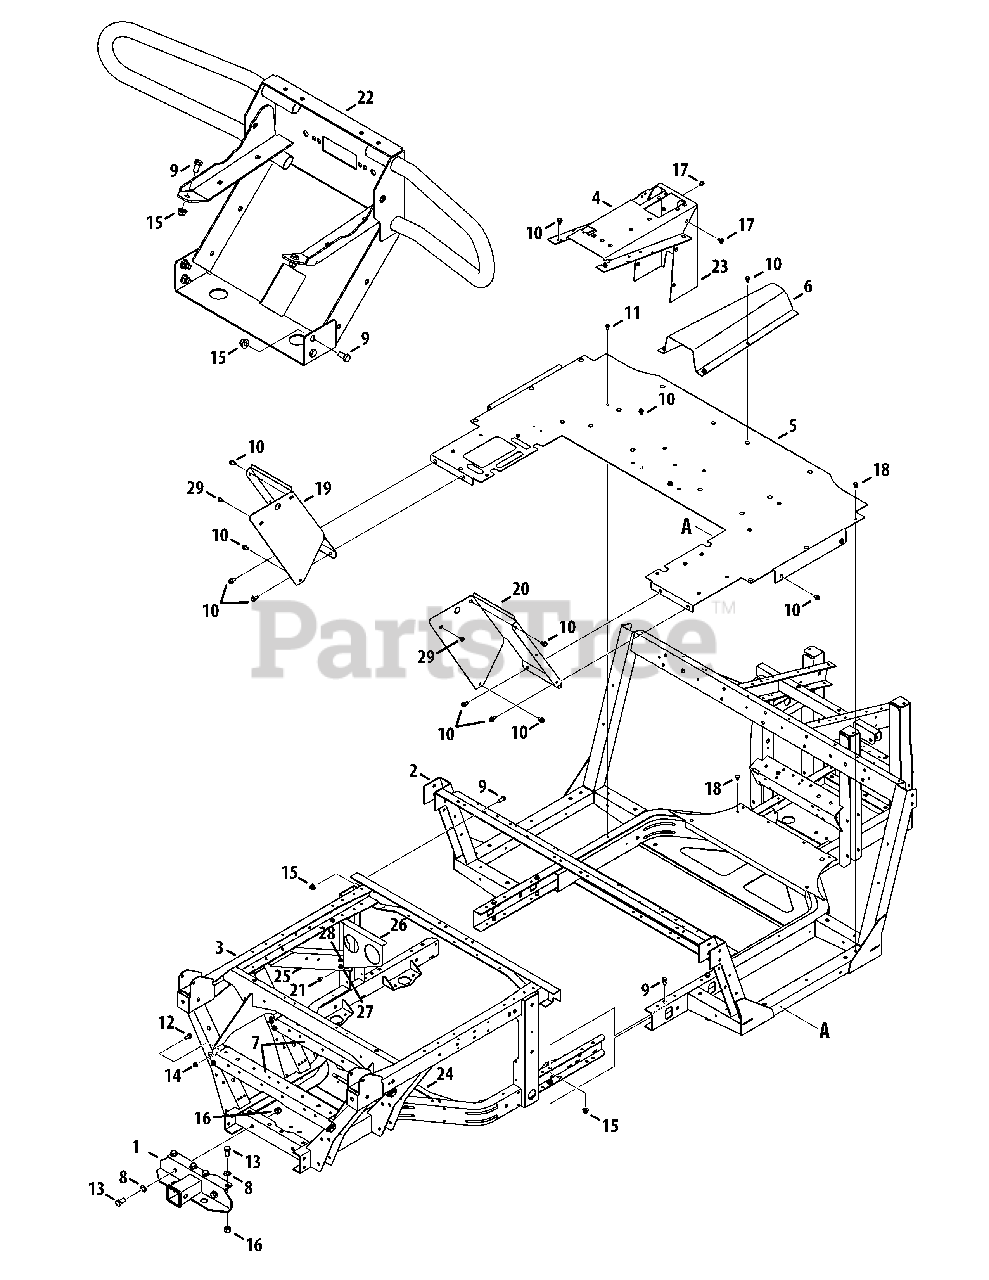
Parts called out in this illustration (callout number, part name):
1	Hitch Assembly, receiver Rr
2	Frame Assembly, front, uv
3	Frame Assembly, rear, uv
4	Plate, console, 4x4, top
6	Cover, front, 4x4
7	Channel, support, rear
8	Washer, Flat, .510 x 1.00 x .060
9	Screw, 3/8-16 x .75, gr5, std
10	Screw, tt, 5/16-18 x 0.750
11	Screw, ab, 1/4-14, 0.625
12	Hex Head Screw, 5/16-18 (4x2)
12	Screw, Hxflg, 5/16-18 (4x4)
13	Screw, 1/2-13, 1.25, gr5, std
14	Nut, Flange Lock, 5/16-18, Nylon
15	Nut, Flange Lock, 3/8-16, Nylon
16	Nut, Hex Lock, 1/2-13, Nylon
17	Screw, tt, 5/16-18 x 0.500
18	Clip, Panel, ret,
19	Bracket, Lh, Shield
20	Bracket, Rh, Shield
21	Screw, tt, 1/4-20 x .500
22	Bumper Assembly, front
23	Plate, console, 4x4, front
24	Bracket Assembly, ISO, Trans/ Eng
25	Bracket Assembly, Air Filter Mnt
26	Bracket Assembly, Supt, Hose
27	Hex Head Screw, 1/4-20 x .620
28	Nut, Flange Lock, 1/4-20
29	Screw, tt, 1/4-20x.625, hxindwsh
